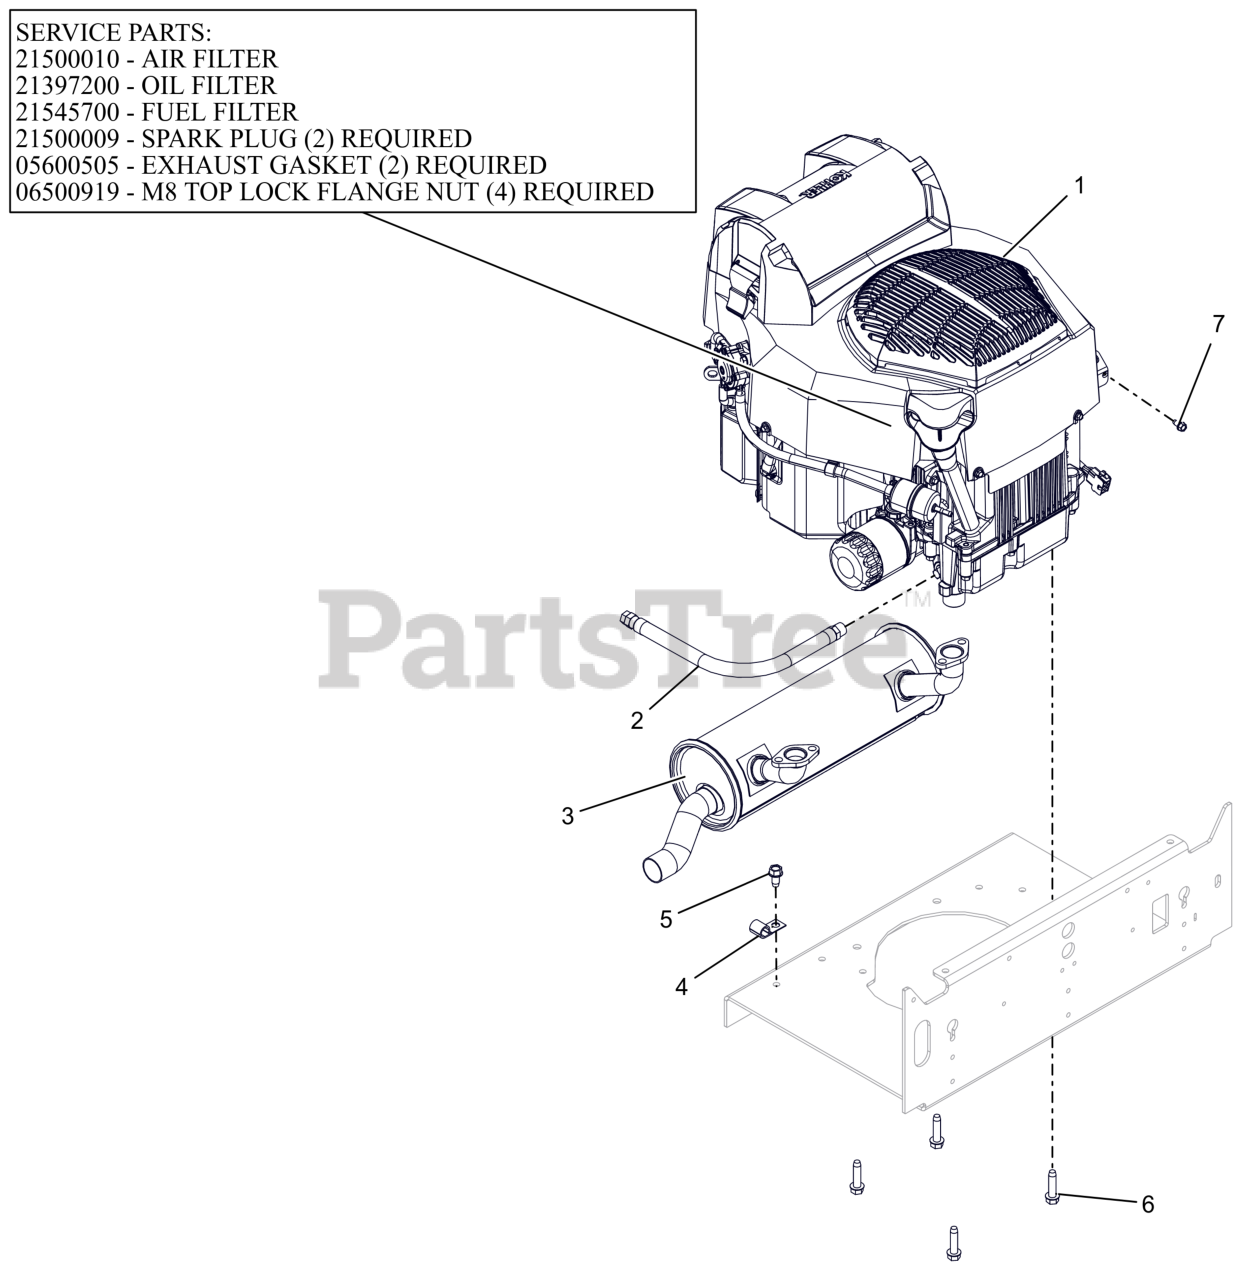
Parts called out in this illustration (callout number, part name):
1	ENGINE, KOHLER ZT740 CONFIDANT
2	HOSE, OIL DRAIN
3	MUFFLER, ZT730/ZT740
5	SCR,TAP .375-16X.75 HWH TR ZCC
6	SCR-TAP .38-16X1.50 HWH ZCC
7	SCR-TAP .25-20X.50 HWH ZCC
